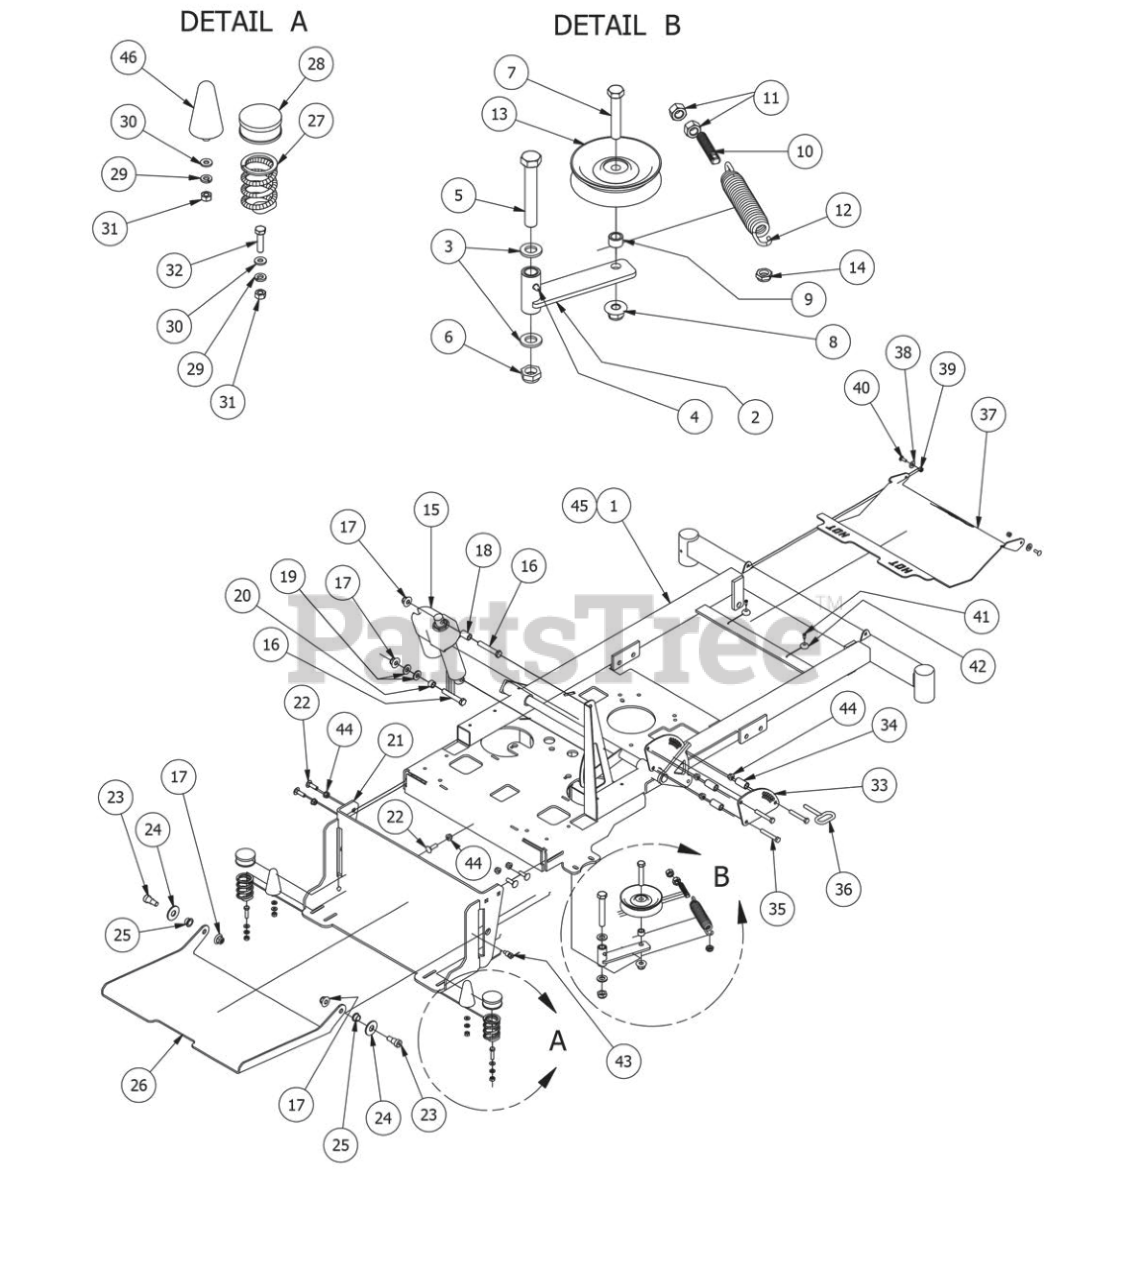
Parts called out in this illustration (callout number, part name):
1	Stand On Frame 2012 (54" Decks)
2	Stand-On Pump Idler Bracket
3	.635 ID Plastic Washer
4	1/4" Drive in Grease Fitting
5	5/8" x 4" Hex Bolt
6	5/8" Nylock (1/2 Jam)
7	1/2" x 2 3/4" Hex Bolt
8	1/2-13 Nylon Flange Nut-Orange
9	1/2 x 1/2 Spacer
10	All Thread-pump Idler Tensioner
11	1/2" Hex Nut
12	2009 Deck/Pump Idler Spring
13	4 3/4" Idler Pulley
14	1/2" Nylcock Nut (1/2 Jam)
16	1/2-13 x GR 5 Hex Bolt Zinc
17	1/2-13 Nylon Flange Nut-Orange
18	.502 x .750 x 1.25 Length Spacer
19	.505 Nylon Spacer
20	1/2 x 1/2 Spacer
21	Stand Frame Support
22	3/8" x 1 1/4" Carriage Bolt
23	5/8" x 5/8" Shoulder Bolt
24	5/8" Flat Washer
25	Bronze Bushing - SF - 2024-8
26	Stand Plate for Stand On
27	Seat Spring
28	Spring Cap Cover
29	5/16" Lock Washer
30	1/4" Flat Washer
32	5/16 x 1 1/4 Hex Bolt
33	Height Indicator Plate Stand On (Bolt on)
34	.502 ID X.75 OD X 1.500 Leng
35	3/8 x 2 1/2 Hex Tap Bolt
36	Pin And Lanyard
37	Floor Panel Stand On
38	.360 ID Plastic Washer
39	1/4" Nylock Nut
40	1/4" x 3/4" Carriage Bolt
41	#10 x 1/2" Self Taping Screw
42	Button Bumper
43	Deck Height Pin-Stand On-New
44	3/8" Nylock Flange Nut
45	Stand On Frame (48" Decks)
46	Rubber Cone-1621-153
